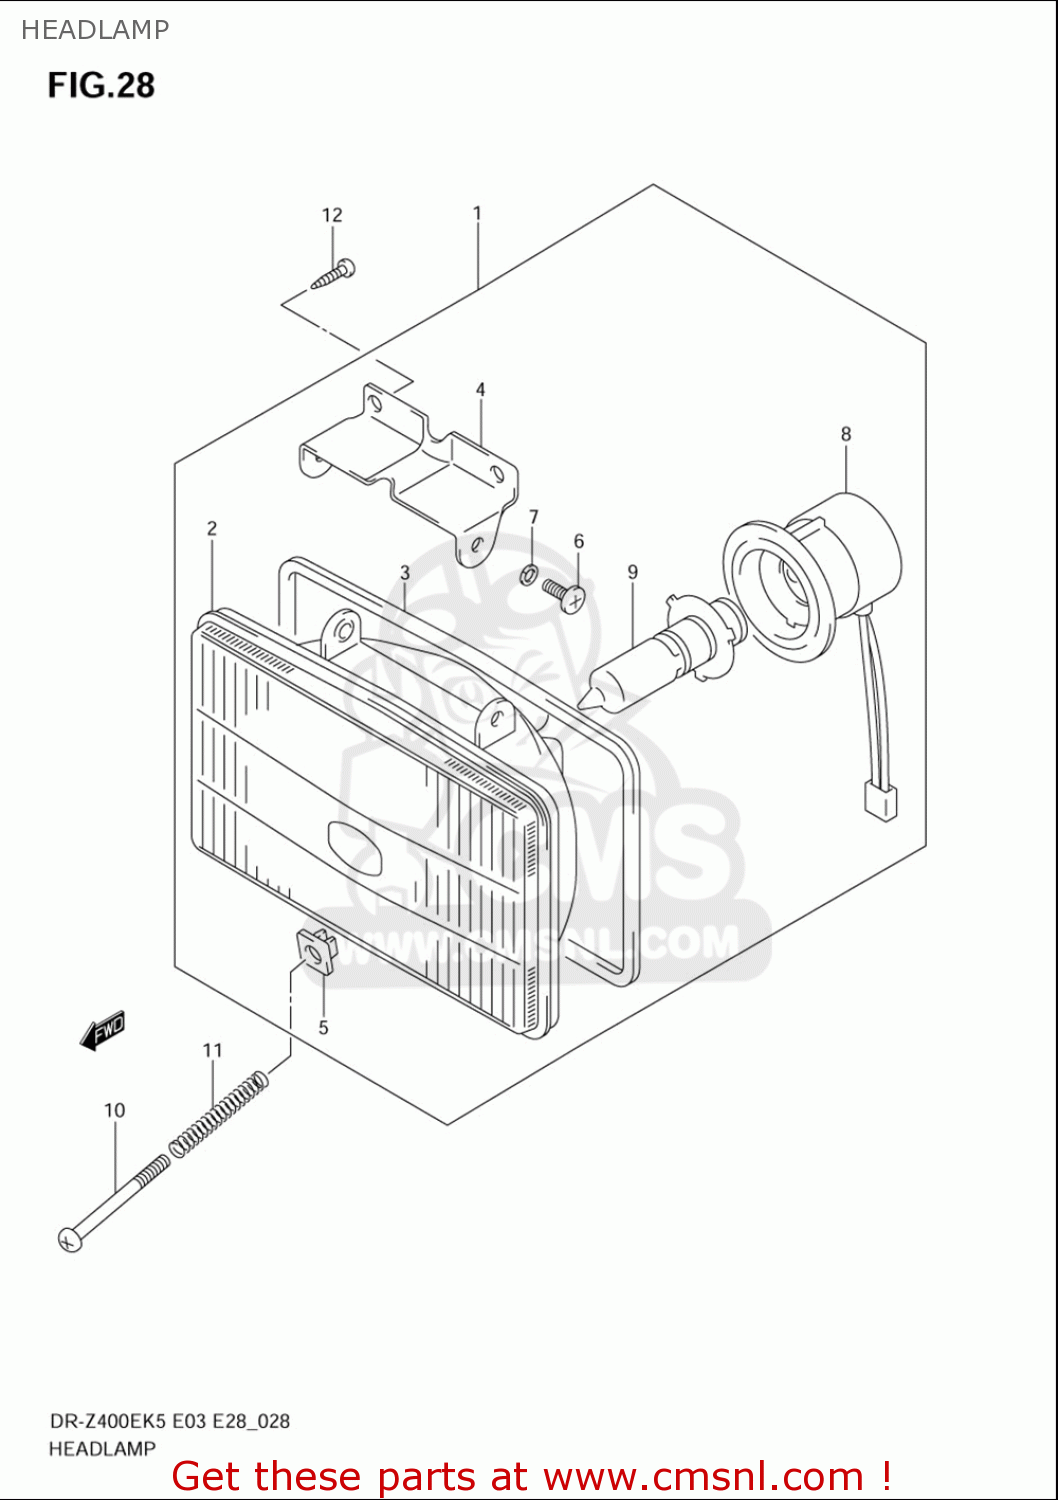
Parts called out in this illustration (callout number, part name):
1	HEADLAMP ASSY
2	UNIT,LAMP
3	GASKET,HEADLAMP (NAS)
4	BRACKET,LAMP
5	NUT,ADJUSTING
6	SCREW
7	WASHER,LOCK
8	SOCKET
9	BULB(12V35/36.5W)
10	SCREW(4X75)
11	SPRING
12	SCREW
